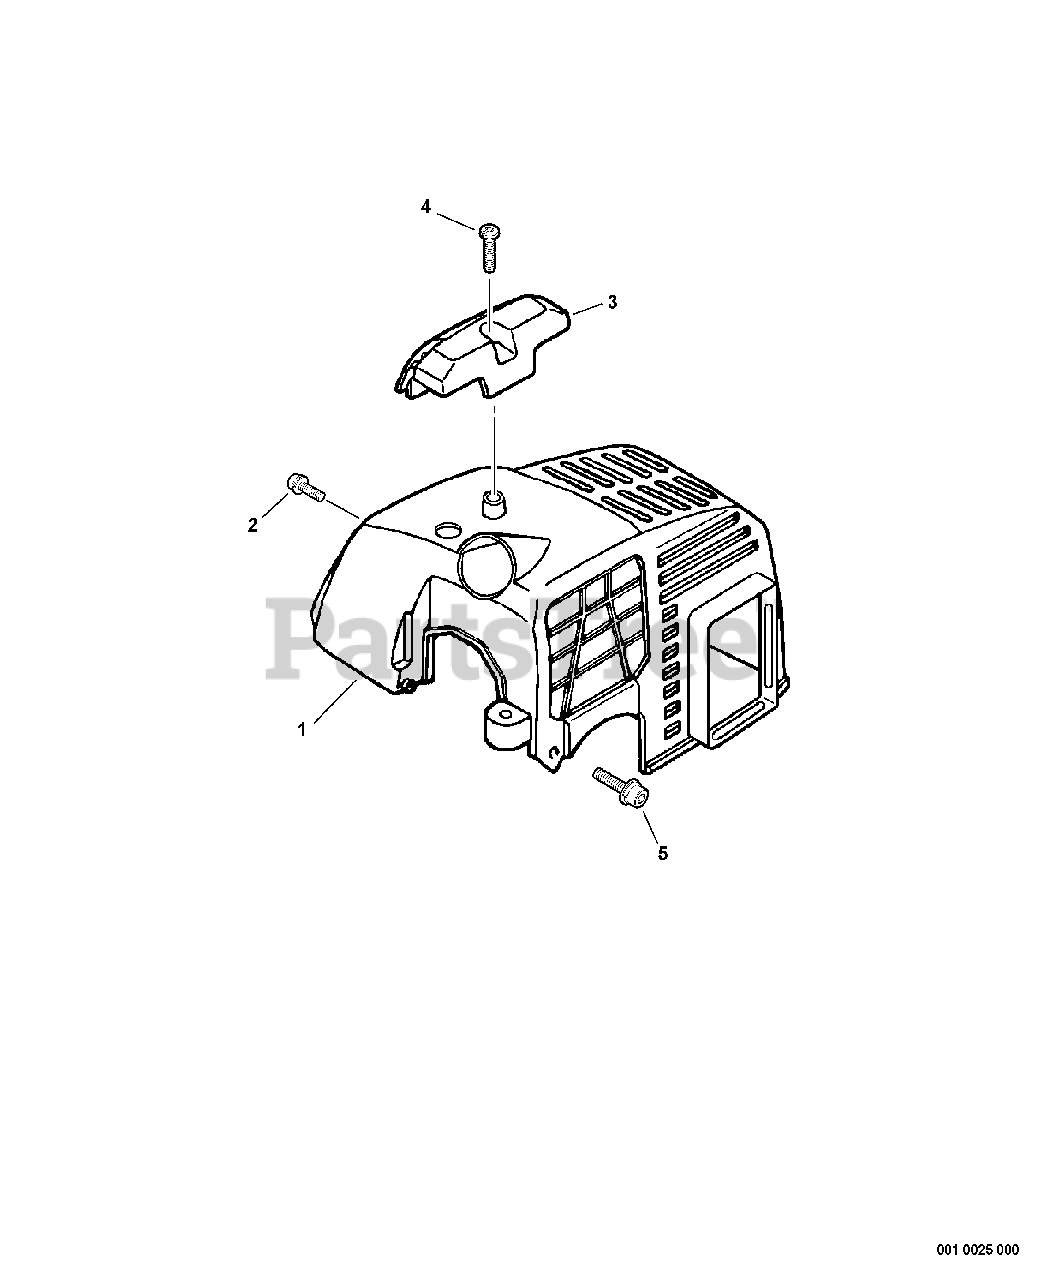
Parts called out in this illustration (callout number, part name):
1	COVER, ENGINE
2	SCREW - 4X12
3	GUARD, TOP - BLACK
4	SCREW - 5X16 -- TAPPING
5	SCREW - 4X16
